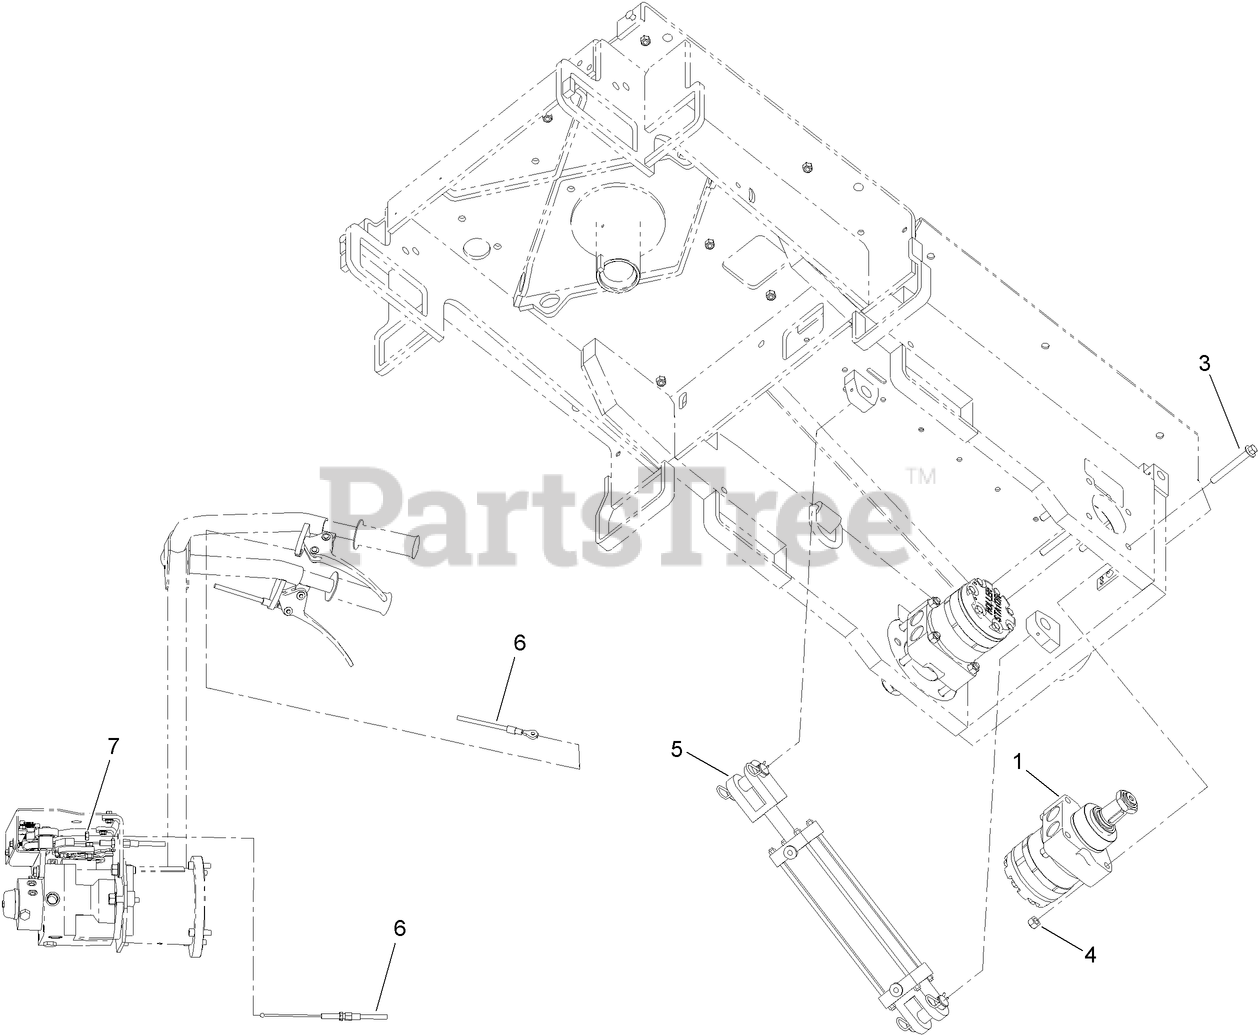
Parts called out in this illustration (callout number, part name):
1	HYD GEAR MOTOR ASM
3	SCREW-HHF
4	NUT-HEX
5	HYD CYLINDER ASM
6	CABLE-CONTROL
7	NUT-HJ
